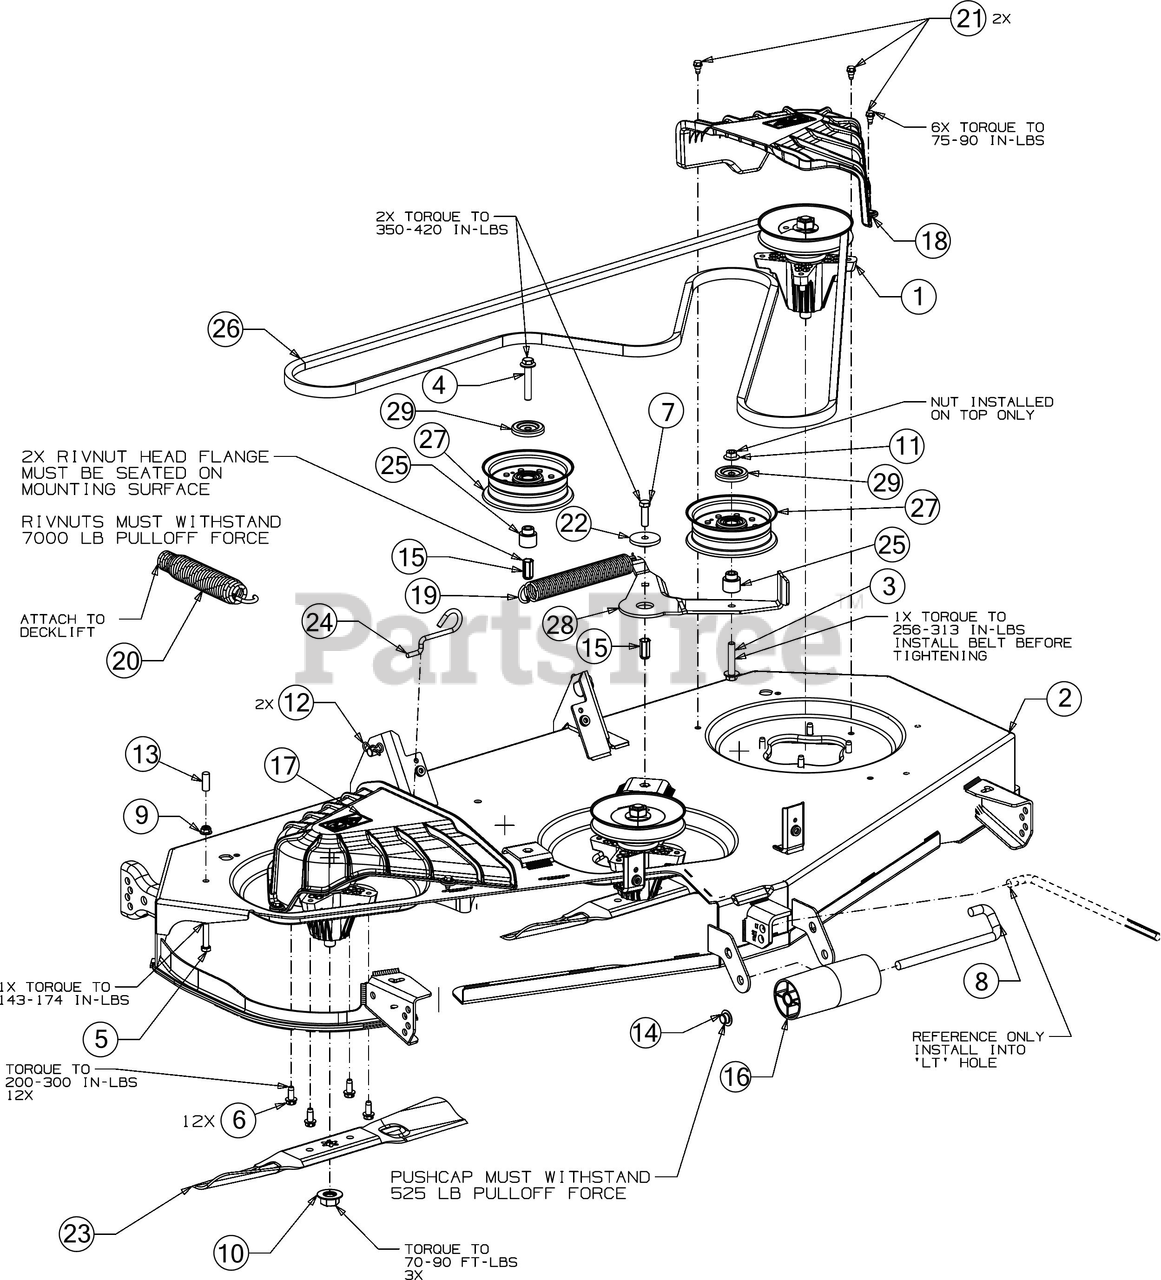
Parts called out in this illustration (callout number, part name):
1	SPINDLE ASSEMBLY
3	SCREW 3/8-16 x 2.0
4	SCREW 3/8-16 x 2.0
4	SCREW 3/8-16 x 2.25 GR5
5	SCREW 5/16-18 x 1.5 LG
7	SCREW 3/8-16 x 1.25 GR5
8	ROLLER PIN 1/2 x 7.31
9	FLANGE LOCK NUT 5/16-18
11	FLANGE LOCK NUT
12	BOW TIE COTTER PIN
15	NUT RIVET 3/8-16
17	SPINDLE COVER (RH)
18	SPINDLE COVER (LH)
19	EXTENSION SPRING
20	LIFT ASSIST SPRING
21	SHOULDER SCREW 1/4-20 x .50
22	SHOULDER SPACER
23	18.61" BLADE (2N1)
24	DECK SPRING HOOK
25	SHOULDER SPACER
26	V-BELT B SEC x 139 LG
27	IDLER PULLEY 4.50" DIA
29	IDLER PULLEY CAP
